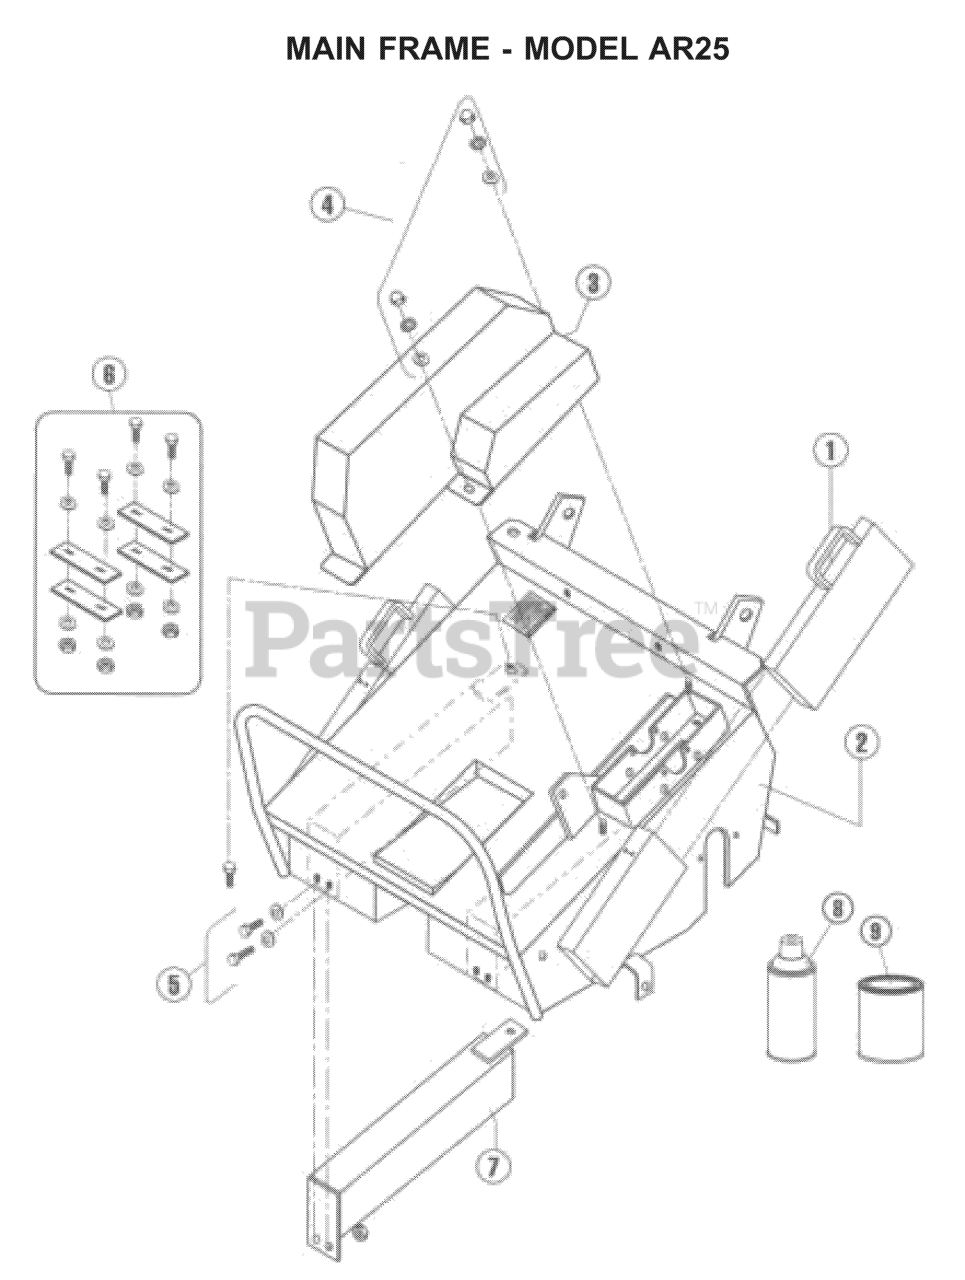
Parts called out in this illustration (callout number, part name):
1	WEIGHT, 36LBS
3	DRIVE GUARD
4	FASTENER KIT
5	FASTNER KIT
6	PLATE KIT FOR HONDA
7	36 IB WEIGHT, MOUNTED
8	PAINT 12.5 OZ SPRAY ORANGE
